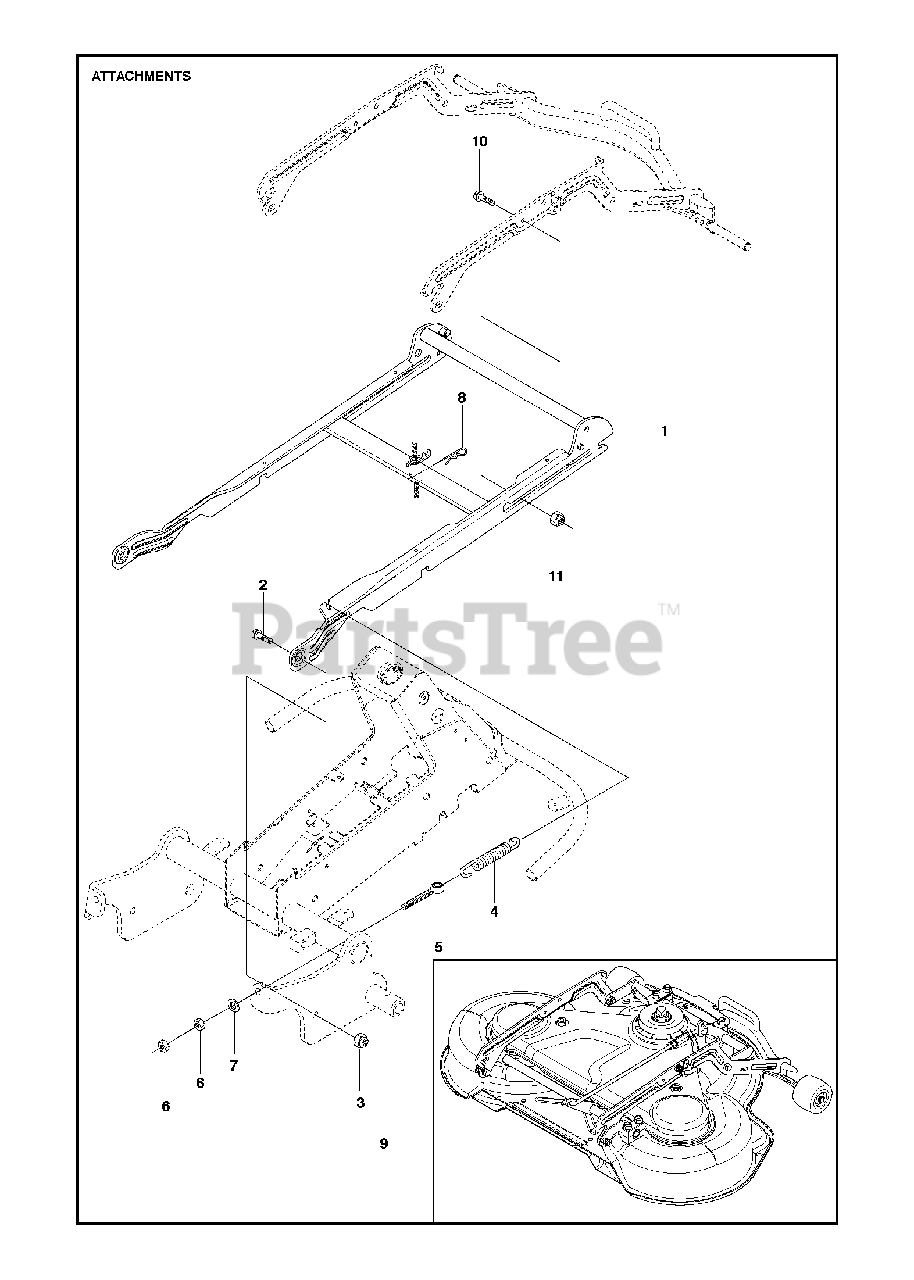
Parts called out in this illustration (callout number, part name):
7	WASHER
10	COLLAR SCREW
11	LOCKNUT M8
